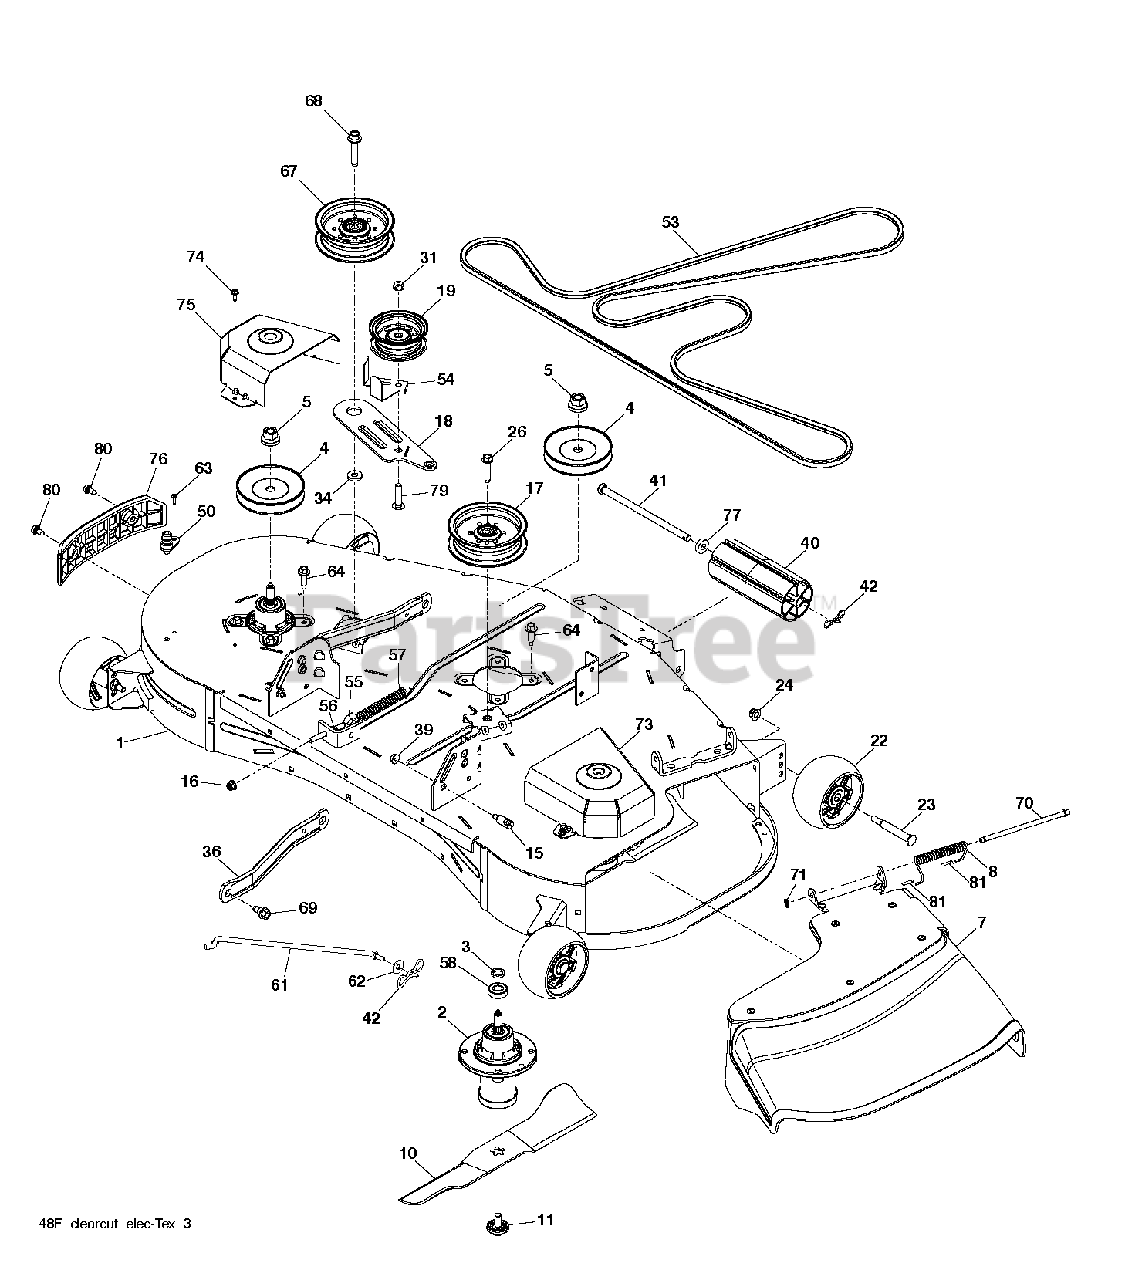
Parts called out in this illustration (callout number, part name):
1	DECK KIT.SVC.48.CC.ASM.668
2	MANDREL ASM, CAST IRON
3	WASHER.SPACER.MANDREL
4	MANDREL PULLEY
5	NUT.FLANGE.LOCK.TOP
7	DEFLECTOR.ASM.48".CLRCT.RES.OR
8	SPRING.42.FCS.DEFLECTOR
10	BLADE.BAGGER.RES.CLRCT.48".BLK
11	BOLT.WASHER.ASM.7/16-2
15	STUD.FASTNER.W/ANTI-ROTATE
16	5/16-18 NYLOC FLANGE NUT
17	PULLEY.IDLER.MWR.STATI.LH
18	ARM.PNT.CLUTCHING.EDIP
19	PULLEY.IDLER.48"PRIMARY
22	Gage Wheel, Rally
23	BOLT.SHOULDER.3/8-16X3-5/8.
24	NUT 3/8-16 HEX FLG NYLOC ZD
26	SCREW.7/16-14 X 2.125.WASHER
31	NUT LOCK FLG 3/8-16 UNC
36	ARM.SUSPENSION.MOWER
39	NUT LOCK HEX FLANGE 5/16-18
40	NOSE ROLLER 48"
41	ROD.ROLLER.NOSE.NARROW.48"
42	PIN.COTTER.5/16.BOW TI
50	PORT.WASHOUT
53	BELT.DECK.TRACTOR
54	GUARD, BELT
55	EYE BOLT 5/16 X 3.50
56	NUT 5/16C WHIZ
57	SPRING.EXTN.42.FCS.TR.DECK.DRV
61	ROD.ANTI.SWAY.48/54"TE
62	WASHER
63	SCR 1/4-20X5/8 HEX SELF TAP ZD
64	BOLT.HEX.WASHR.HED.313-18X1.19
67	PULLEY.IDLER.2006
68	SCREW LT
69	BOLT.SHOULDER
70	ROD.HINGE
71	NUT PUSH M
73	COVER.PNT.MANDREL.RH.GREY
74	SCREW.1/4-20X5/8
75	COVER.PNT.MANDREL.LH.
76	BUMPER.ASM.SIDE.TRIM.CLRCUT.48
77	BUSHING.NOSE.ROLLER
80	SHOULDER BOLT 5/16-18TT
81	CAP-SLEEVE LT
